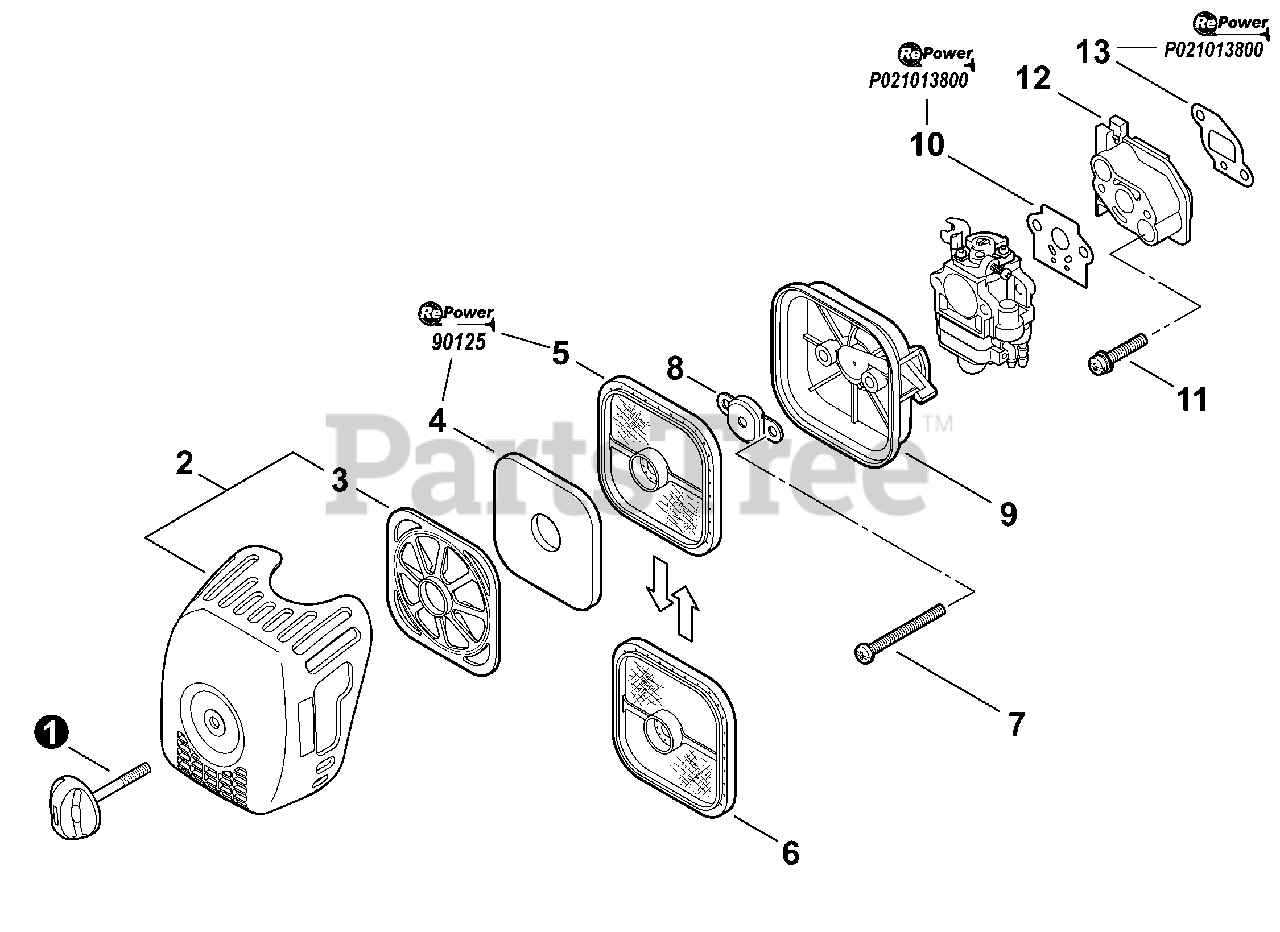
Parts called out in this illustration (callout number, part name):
1	THUMBSCREW
2	AIR CLEANER COVER KIT
3	RETAINER, PRE-FILTER
4	PRE-FILTER - FOAM
5	FILTER, AIR - DOUBLE LAYER
6	FILTER, AIR - SINGLE LAYER
7	SCREW - 5X60
8	PLATE, PREVENT
9	CASE, AIR CLEANER - BLACK
10	GASKET, INTAKE
11	SCREW - 5×30
12	INSULATOR
13	GASKET, INTAKE
